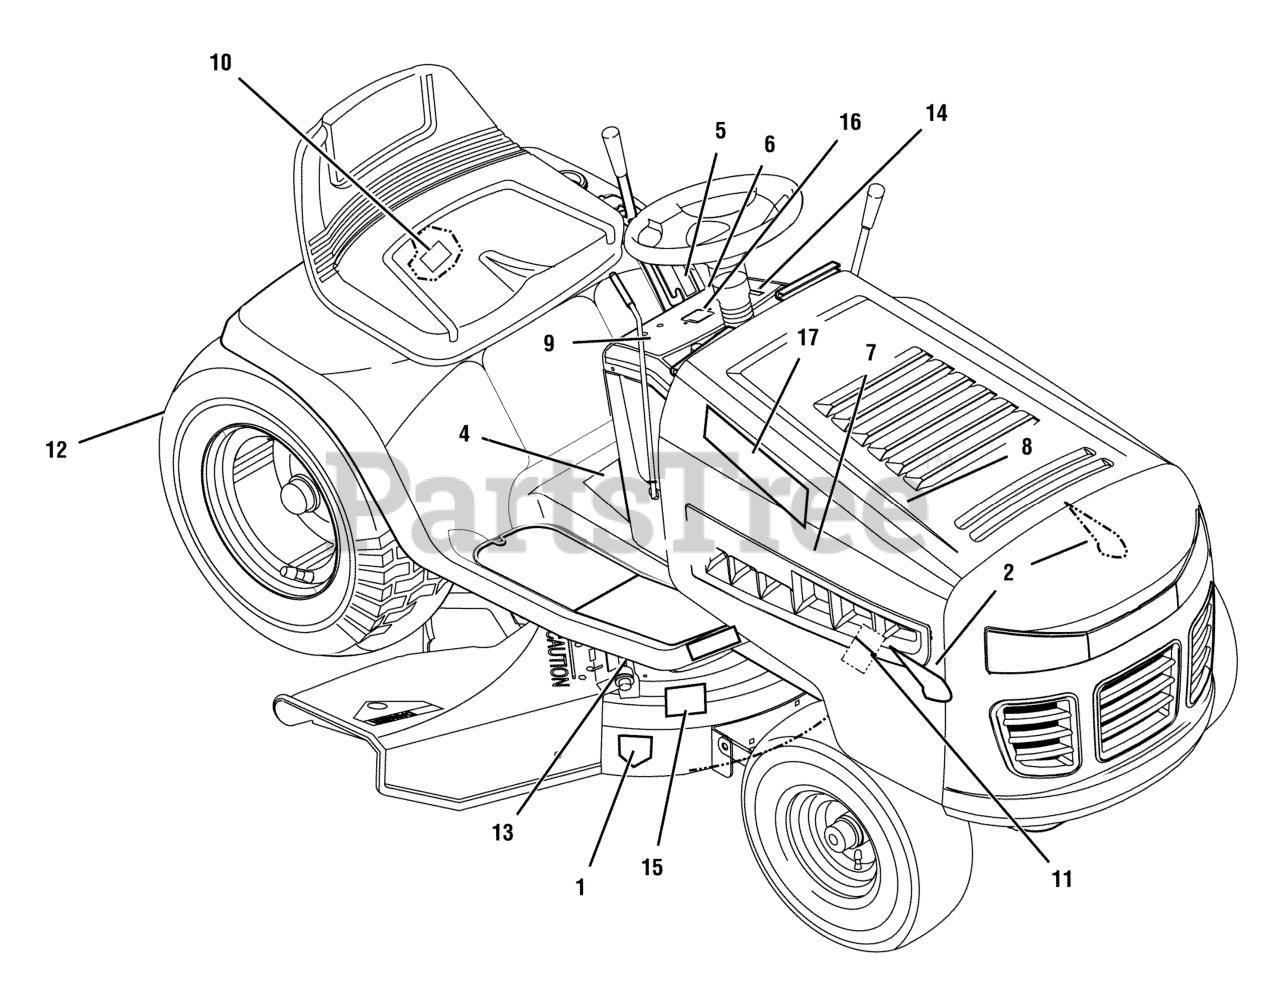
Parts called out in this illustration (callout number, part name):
1	DECAL, Cut Fingers Symbol
2	DECAL, 175/107 L.H. & R.H.
4	DECAL, Warning Export
5	DECAL, 7 Position Cut Height
6	DECAL, Deck Level
7	DECAL, No Step Export
8	DECAL, Brake/Clutch Export
9	DECAL, Engage & Park Brake
10	DECAL, Variator LG SD 1-2 FDR SH
11	DECAL, Heat Shield Warning
12	DECAL, Warning Load Limit Export
13	DECAL, Warning Pinch Point
14	DECAL, Throttle Twin
15	DECAL, 100db Export
16	DECAL, Gas Gauge
17	DECAL, Murray L.H & R.H
18	DECAL, Variator Drive
